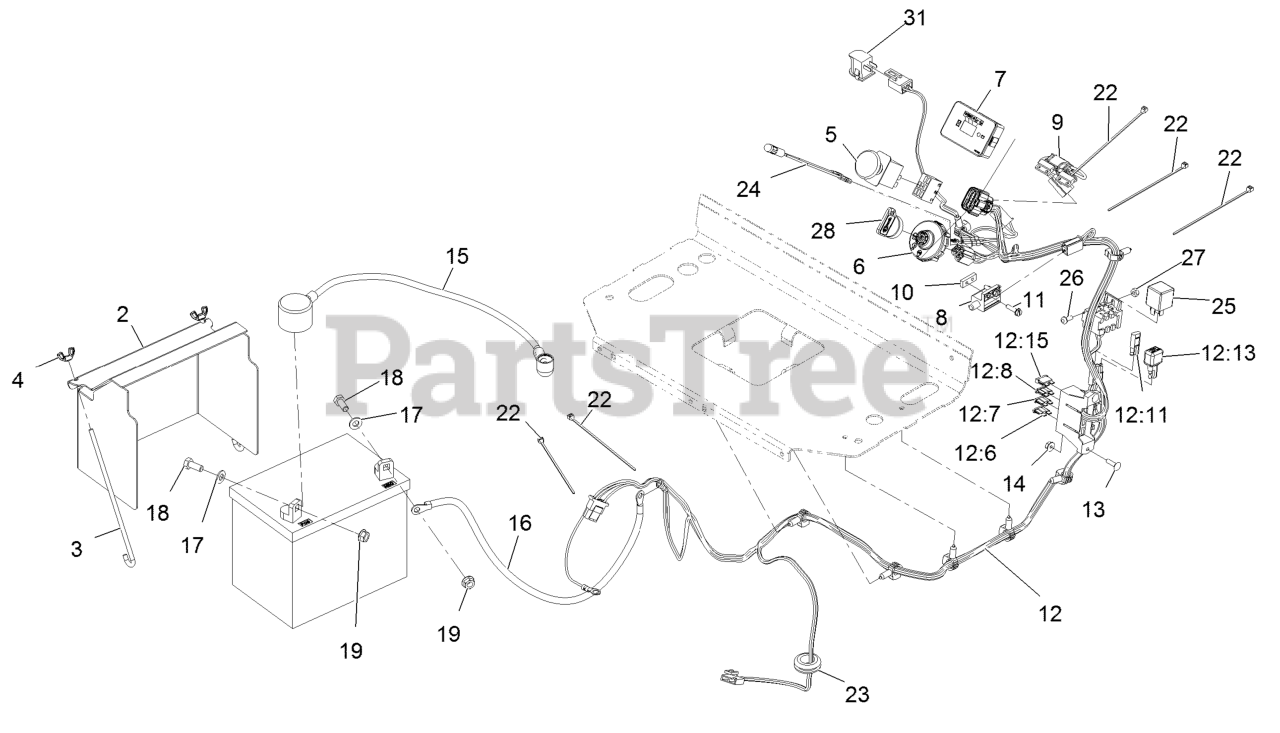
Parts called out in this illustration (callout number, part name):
2	COVER-BATTERY
3	BOLT-HOLDDOWN
4	WINGNUT
5	SWITCH-PTO, ON-ON
7	MODULE-HOUR METER
8	SWITCH-CLOSED, NORMALLY
9	HARNESS-SWITCH, REED
10	PLATE-TAPPED
11	SCREW-HWH
12	HARNESS, WIRE
12:6	FUSE-BLADE, 30 AMP
12:7	FUSE-BLADE, 25 AMP
12:8	FUSE-BLADE, 10 AMP
12:15	FUSE-BLADE, 15 AMP
13	SCREW-CARR
15	CABLE-BATTERY, POSITIVE
16	CABLE-BATTERY, BLACK
17	WASHER-PLAIN
18	SCREW-HH
19	NUT-HHF, SMOOTH
22	TIE-CABLE
23	GROMMET
24	INDICATOR-LED, RED
26	SCREW-PPH
27	NUT-LOCK, NI
28	KEY-IGNITION
31	SWITCH-BAIL
